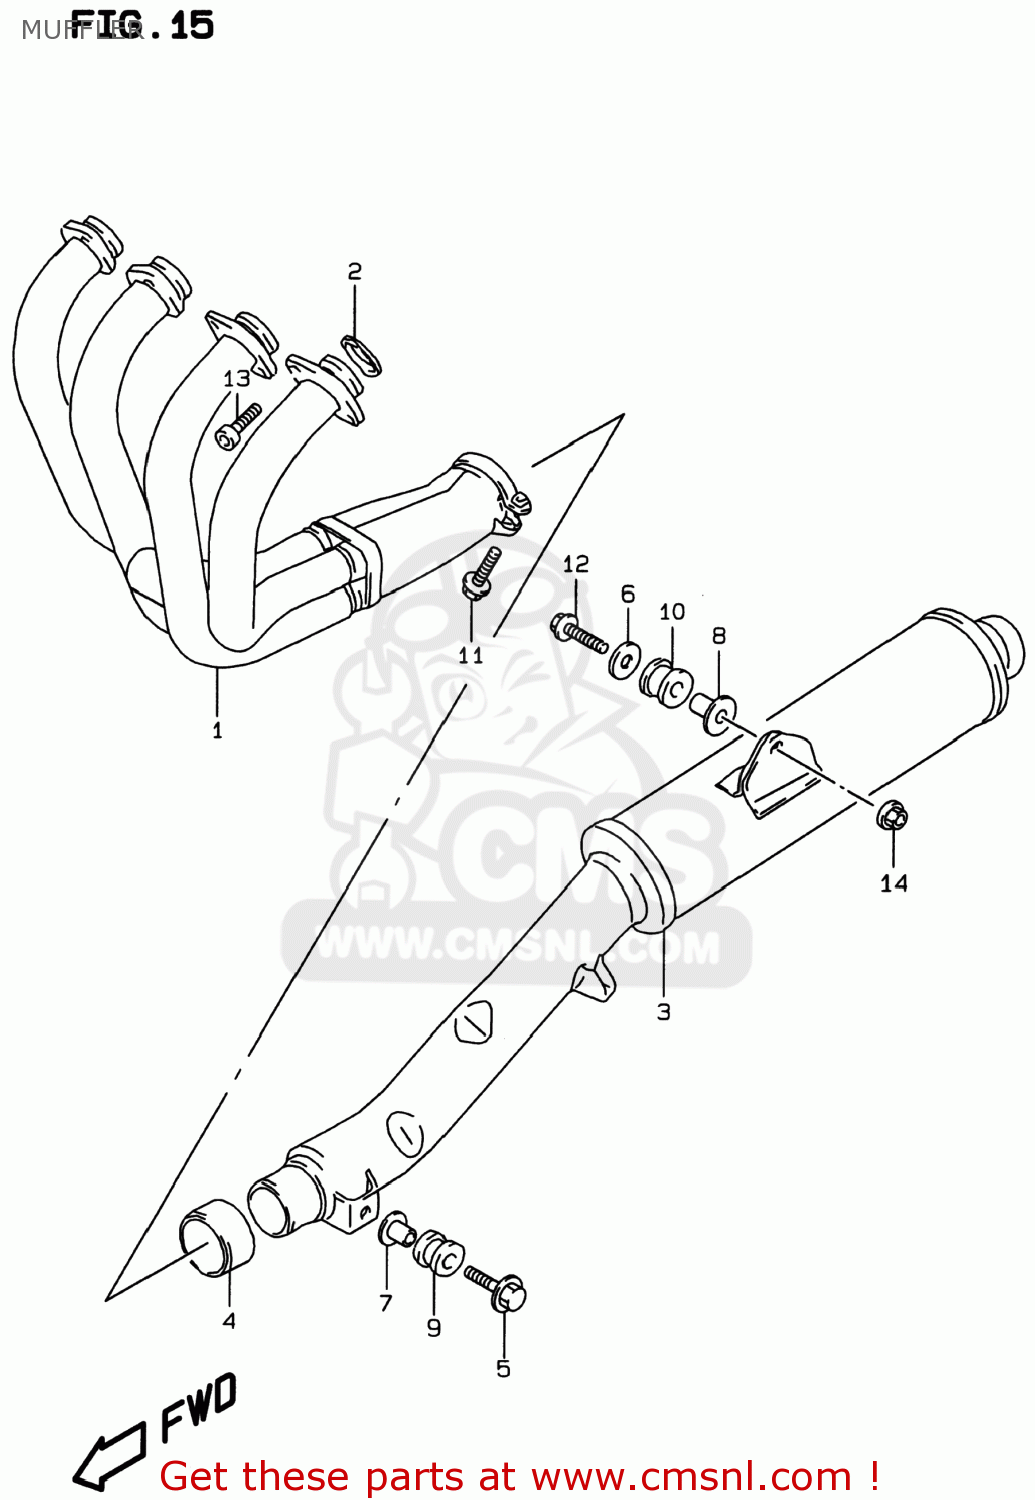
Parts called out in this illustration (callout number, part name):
1	EXHAUST
2	GASKET,EXHAUST (NAS)
3	BODY,MUFFLER
4	CONNECTOR,MUFFLER
5	BOLT 8X40
6	WASHER (8.1X33X1.6)
7	SPACER(8.6X12X24.2)
8	SPACER(8.6X12X27.1)
9	CUSHION
10	CUSHION
11	BOLT
12	BOLT
13	BOLT
14	NUT
